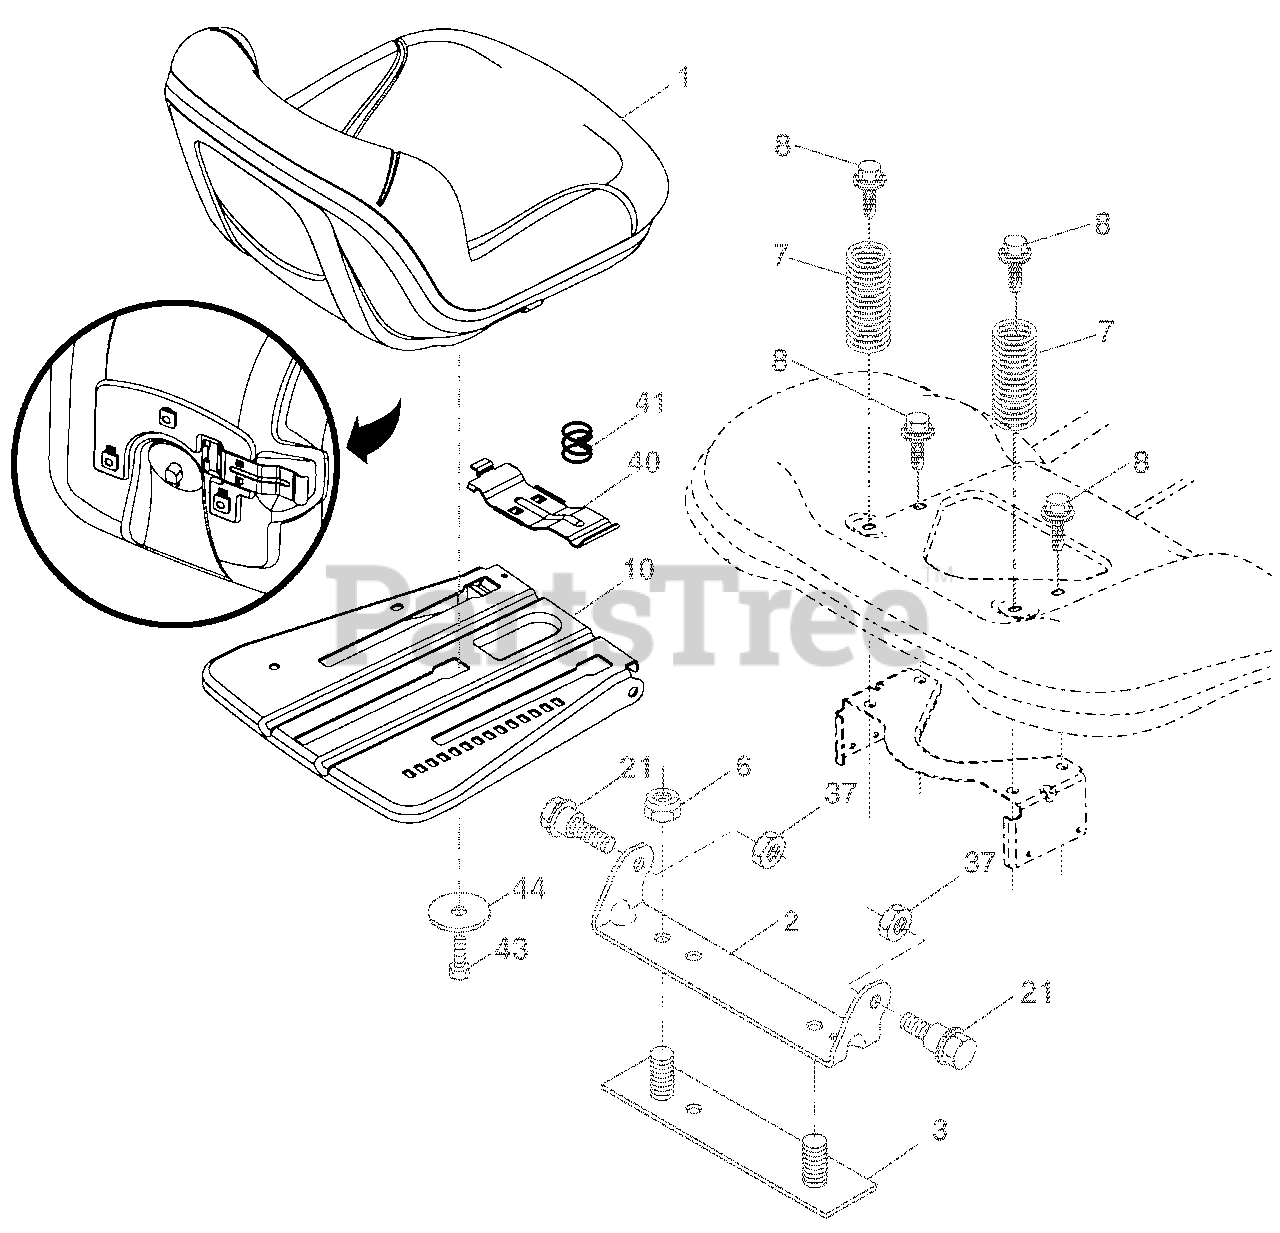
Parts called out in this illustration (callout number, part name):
1	SEAT.TA150.KB/SLD.BLK.ARIENS
2	BRACKET.PIVOT.FENDER.2002
3	STRAP ASM.FENDER.94
6	Locknut, Washer Insert 3/8-16
7	SPRING.SEAT.CPRSN.2.250.BLK.ZI
8	BOLT.5/16-18UNCX3/4 W/SEMS.BLK
10	PAN ASM.SEAT.3PT.
21	BOLT.SHLD.5/16-18 UNC-2A.BLK D
37	Locknut, Washer Insert 5/16-18
40	HANDLE.SLIDE.SEAT.TEX.MILSCO
41	SPRING.LATCH.SEAT.TEX
43	BOLT.FIN.HEX.3/8-16UNC X 3/4
44	WASHER.13/32 X 2 3/8 X 12GA.
